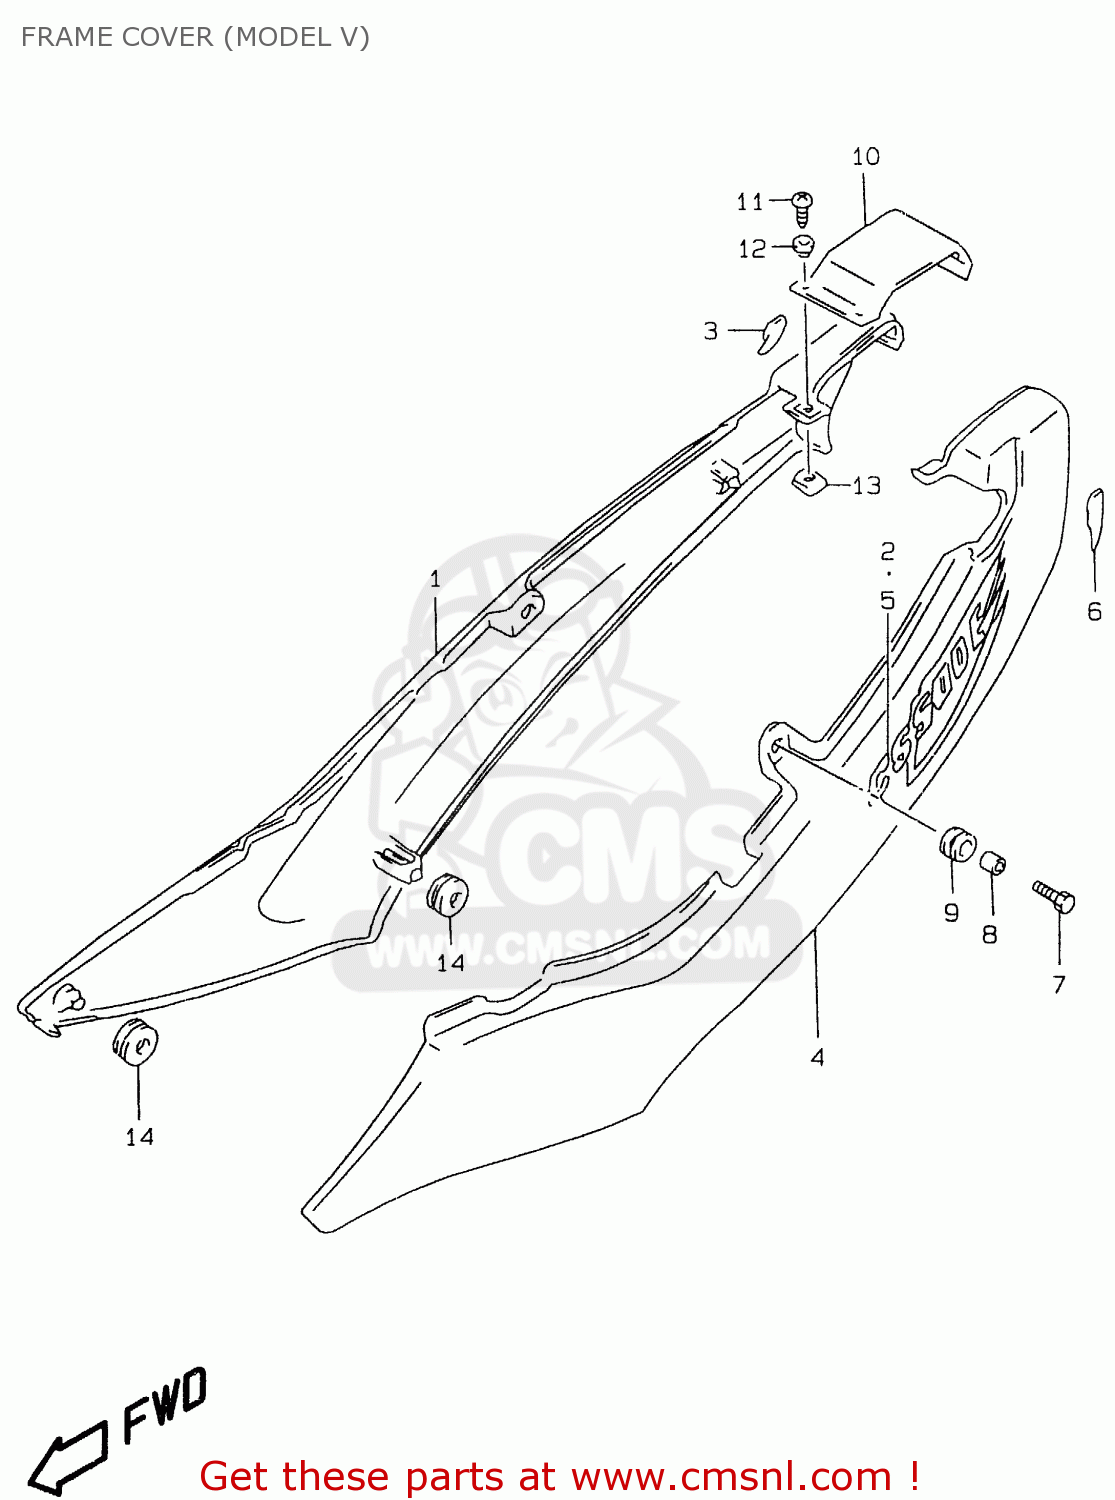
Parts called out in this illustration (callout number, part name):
1	COVER,FRAME,R(RED)
2	TAPE,FRAME COVER,R
3	PROTECTOR,FRAME COVER,R
4	COVER,FRAME,L(RED)
5	TAPE,FRAME COVER,L
6	PROTECTOR,FRAME COVER,L
7	BOLT(6X20)
8	SPACER(6.5X9X9)
9	CUSHION
10	COVER,FRAME CTR
11	SCREW L:12
12	WASHER(5.2X14X1.5)
13	NUT
14	CUSHION
